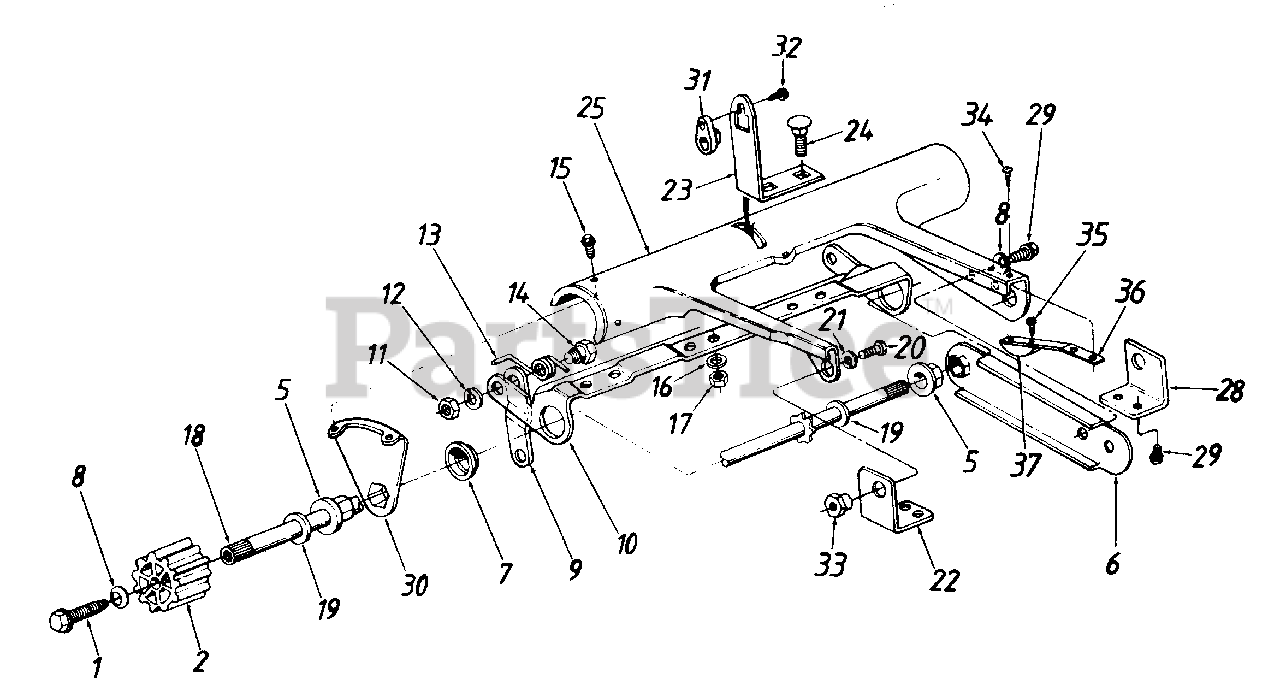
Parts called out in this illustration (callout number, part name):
1	Hex Scr. 1/4-20 x .75" Lg. (Gr. 5)
2	Wheel Drive Pinion
5	Hex Flange Brg. .504" I.D.
8	Bell-Wash. .265" I.D. x .75" O.D.
11	Hex Nut 5/16-18 Thd.
12	L-Wash. 5/16" I.D.
13	Torsion Spring - R.H.
14	Shoulder Bolt .437" Dia.
15	Hex L-Hd. AB-Tap Scr. 1/4" x .62" Lg.
16	L-Wash. 1/4" I.D.
17	Hex Nut 1/4-20 Thd.
18	Drive Shaft Ass'y.
19	Fl-Wash. .531" I.D. x .93" O.D.
20	Hex Bolt 3/8-16 x .5" Lg.
21	L-Wash. 3/8" I.D.
32	Hex B-Tap Scr. #10 x .44" Lg.
33	Shld. Nut .625" Dia. x .165" Lg.
34	Truss Mach. B-Tap Scr. #10 x .5" Lg.
35	Hex B-Tap Scr. #10 x 3/8" Lg.
36	Cantilever Spring
37	Chain Tensioner
